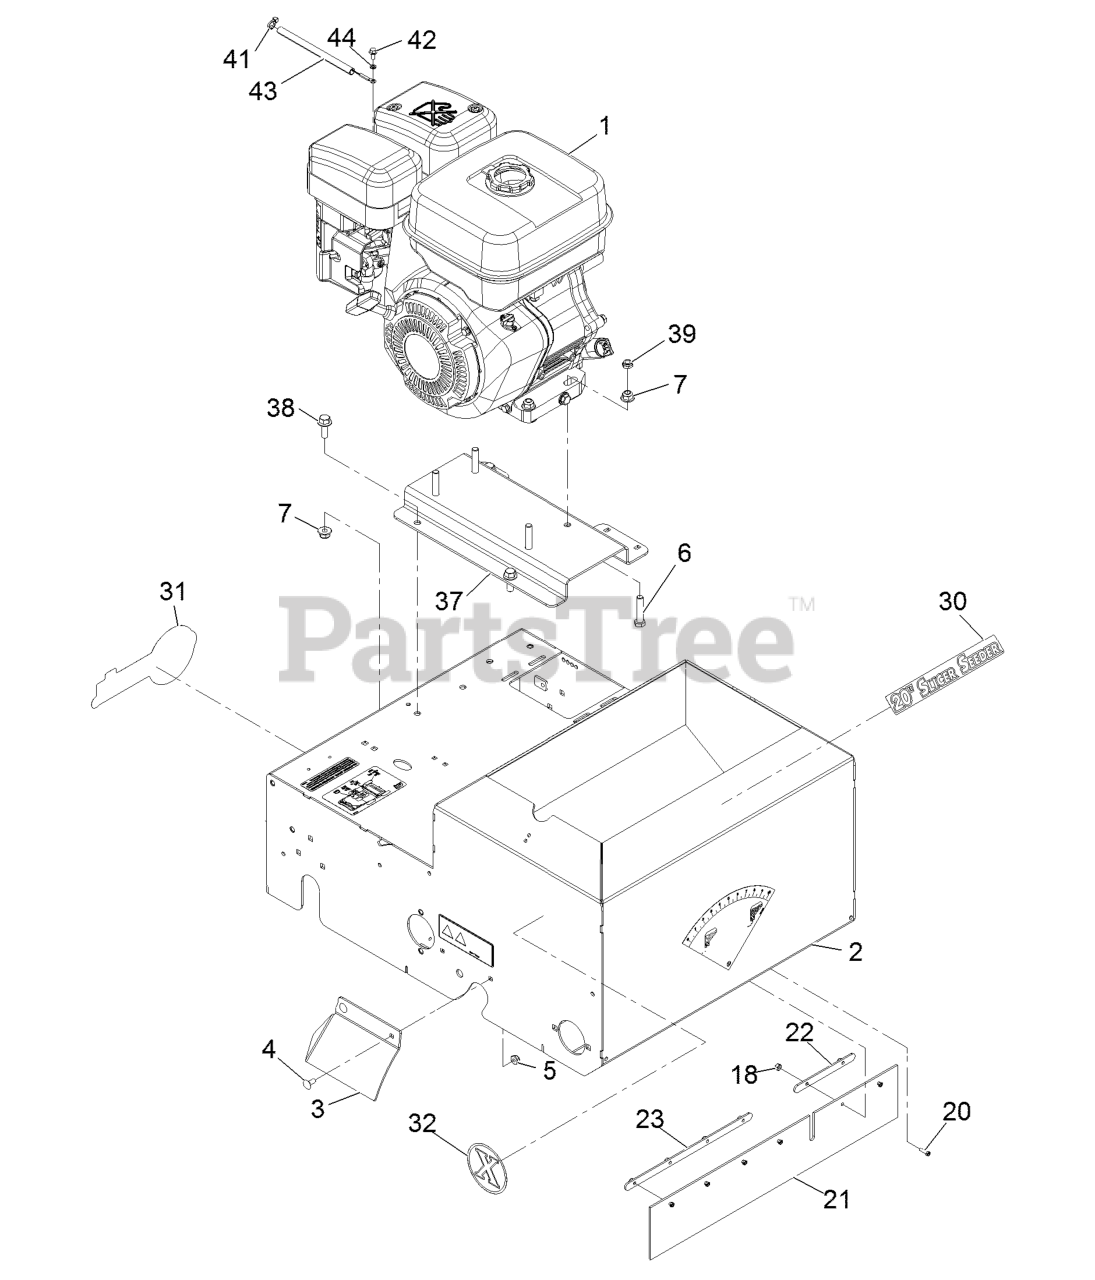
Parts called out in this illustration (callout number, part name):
2	FRAME ASM
4	SCREW-CARR
6	SCREW-HH
7	NUT-HF, NI
18	NUT-LOCK
20	SCREW-SHH
21	GUARD-DUST
22	PLATE-RETAINER
23	PLATE-RETAINER
30	DECAL-SLICER SEEDER 20
31	DECAL,EXMARK LOGO
32	DECAL-EXMARK X-LOGO 3.26
37	PLATE-ENGINE
38	SCREW-HHF 3/8-16 X 1
41	TIE-CABLE
42	SCREW-HFH
43	RFI-SHEATHING
44	WASHER-LOCK, SPRING
